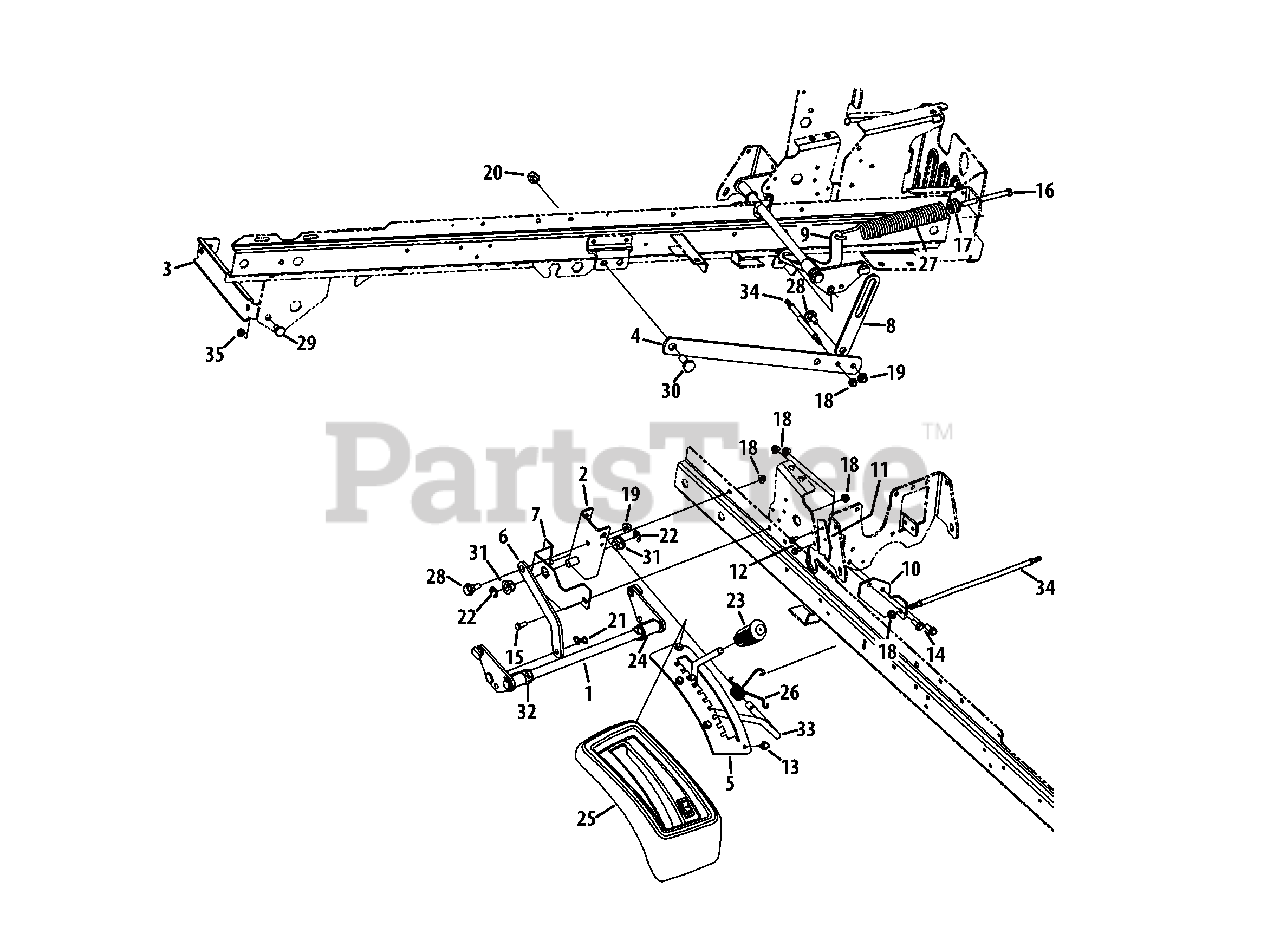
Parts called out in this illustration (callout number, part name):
1	Manual Lift Shaft Assembly
2	Manual Lift Lever Bracket Assembly
3	Front Hanger Bracket
5	Manual Lift Index Bracket
6	Manual Lift Link Plate
7	Manual Lift Lever Mount Bracket
8	Link Lift Plate
9	Extension Spring Plate
10	Sway Bar Mount Bracket
11	Bearing Stop Plate
12	Hex Washer Screw, 1/4-20 x .500
13	Hex Washer Screw, 5/16-18 x .625
14	Hex Washer Screw, 5/16-18 x .875
15	Hex Screw, 5/16-18 x .75
16	Hex Screw, 3/8-16 x 4.25
17	Spring Insert
18	Flange Lock Nut, 5/16-18
19	Flange Lock Nut, 3/8-16
20	Hex Lock Nut, 1/2-13
21	Bow-Tie Cotter Pin
22	E-Ring, .625
25	Lif Manual Cover
26	LH Torsion Spring
27	Extension Spring, 1.485 x 9.68
28	Shoulder Screw, 3/8-16 x .562 x .360
29	Shoulder Screw, 1/2 x .29
30	Shoulder Screw, 1/2-13 x .625 x .36
31	Hex Flange Bearing
32	Hex Flange Bearing
33	Manual Lift Handle Rod
34	Anti-Sway Deck Rod
35	Jam Lock Nut, 3/8-16
